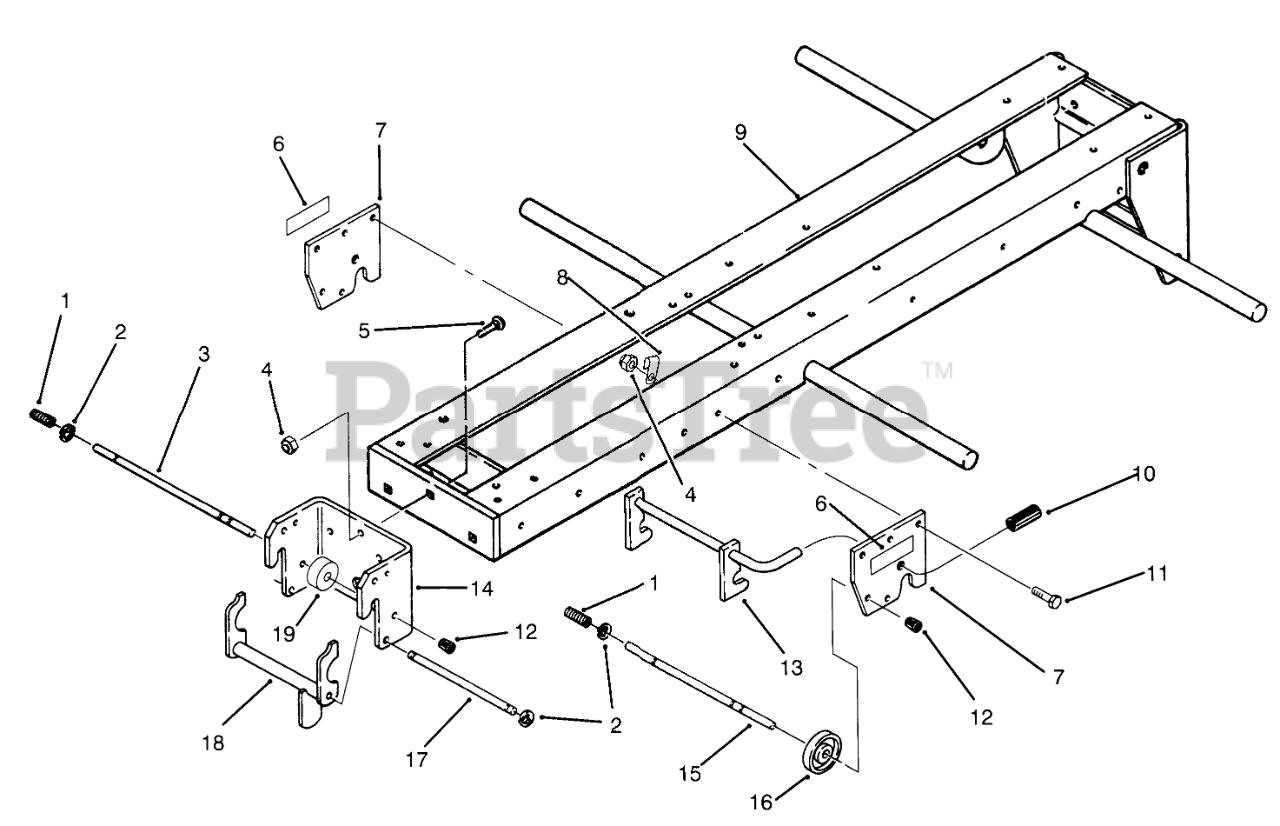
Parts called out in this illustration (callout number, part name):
1	SPRING
2	RING-RETAINING
3	ROD-LOCK
4	NUT-LOCK, NI
5	BOLT-CARR
6	DECAL-ATTACH A-MATIC
7	Hitch Plate
8	CLIP
9	WELD FRAME R
10	GRIP
11	SCREW-HH
12	CAP-ROD, PLUNGER
13	MID HITCH ASM
14	Front Hitch
15	ROD-LOCK
17	ROD-LATCH PIVOT
18	LATCH
